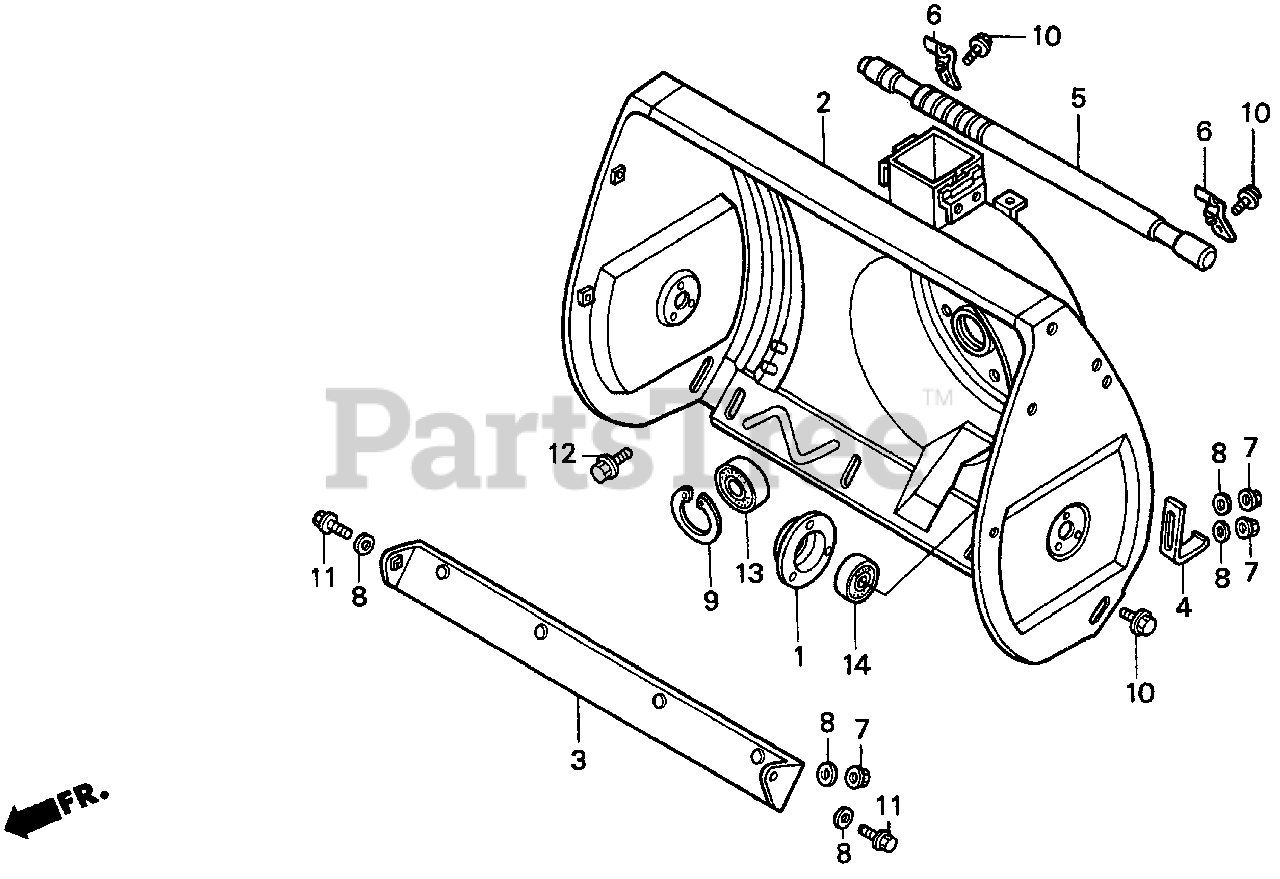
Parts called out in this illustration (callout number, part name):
1	HOLDER, AUGER BEARING
2	HOUSING, AUGER
3	GUARD, AUGER HOUSING (22INCH)
4	SKID, AUGER
5	BAR, HEIGHT ADJUSTMENT
6	BRACKET, HEIGHT ADJUSTMENT BAR
7	NUT, FLANGE (6MM)
8	WASHER, PLAIN (6MM)
9	CIRCLIP (INNER) (47MM)
10	BOLT, FLANGE (6X10)
11	BOLT, FLANGE (6X12)
12	BOLT, FLANGE (8X20)
13	BEARING, RADIAL BALL (6005UU)
14	BEARING, RADIAL BALL (6203UU)
